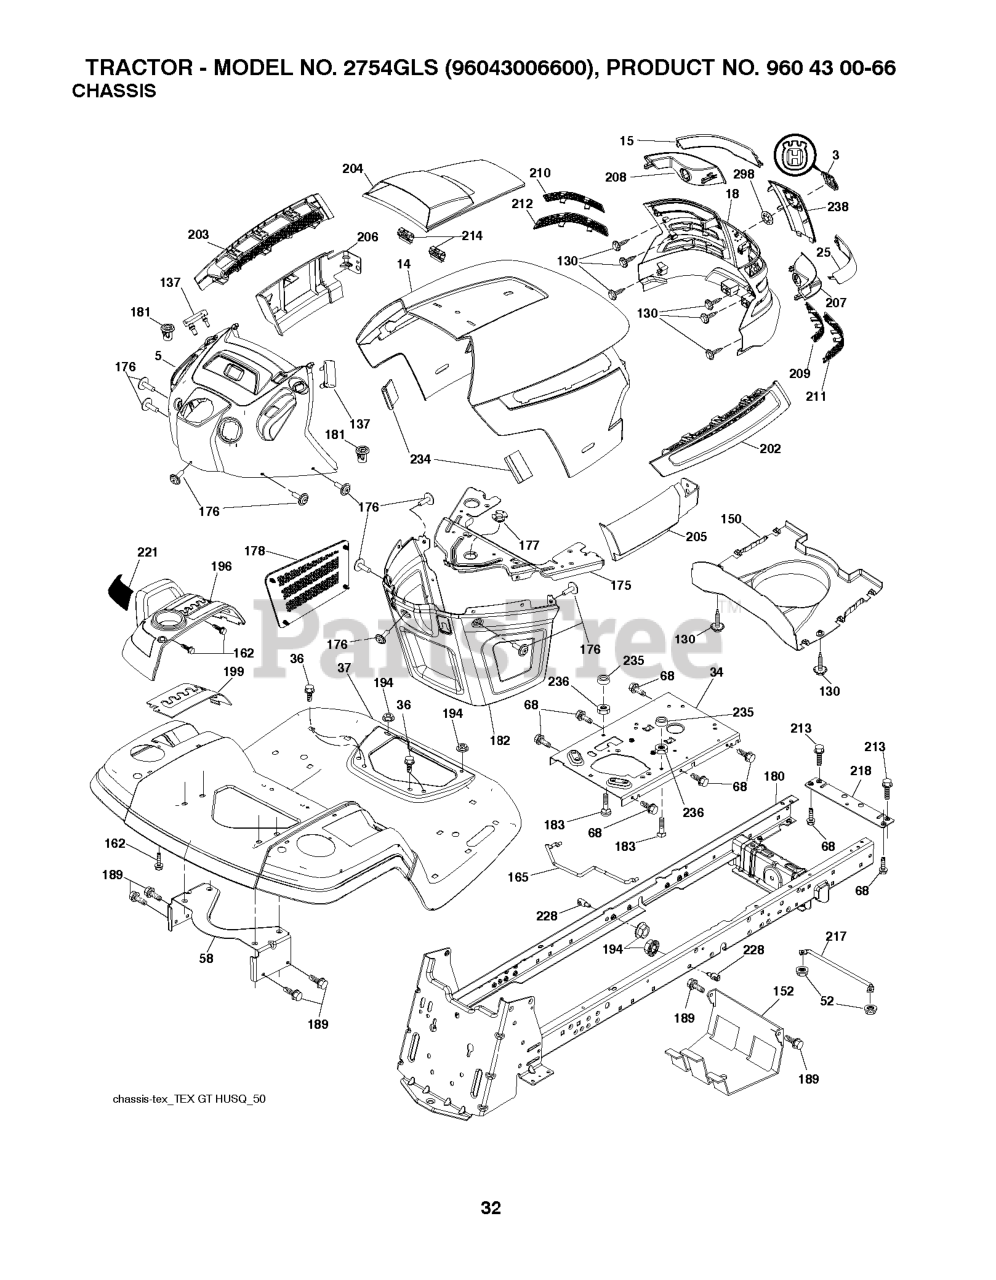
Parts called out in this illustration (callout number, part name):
3	RP LOGO
5	DASH.ASM.GTHUSQTX.RGS.ELECT.CK
14	HOOD
15	LENS.LH.TEX.GT.HUSQ.CL
18	GRILL.ASM.HUSQ.TG/CRD.W/TRIM
25	LENS.RH.TEX.GT.HUSQ.CL
34	PLATE.ENGINE.WELDED.CHASSIS
36	SCREW 5/16"
37	FENDER.PNT.TX.GT.CH/FW.ORANGE
52	LOCKNUT
58	BRKT.SUPPORT.FNDR/TANK
68	Screw 5/16-18 x 1/2 Hex, Self Tapping 5/16-18 x 1/2
130	SCREW.#10 X 0.750.BOS
137	BUMPER DASH
150	AIR.DUCT.HOOD.TEX.GT.HUSQ
152	SHIELD.BROWNING.W/TEX
161	CONSOLE.FUEL.WINDOW.HU
162	SCREW.HI-LO.CONSOLE
165	SUPPORT.TANK.REAR.W/TEX
175	PLATE.CROSSMEMBER.HUSQ
176	SCREW.#10-24X5/8.RN.QU
177	BUSHING, STEERING
178	CARGO.ASM.NET.TXGT.W/C
180	CHASSIS.GT.SLOPED.DRAWBAR.
181	BUSHING.MNT.FEND.CRGO.
182	DASH.LOWER.COMMON.12V.ADAPTOR
183	BOLT.5/16-18X1-1/4 FULL.THREAD
189	SCREW
194	NUT LOCK HEX FLANGE 5/16-18
196	CONSOLE.ASM.DCKLFT.W/RF.HQ.DLR
199	PLATE.DECK.LIFT.HUSQVARNA.GT
202	VENT.SIDE.HOOD.HUSQ.RH.GREY
203	VENT.SIDE.HOOD.HUSQ.LH.GRAY
204	HOOD VENT
205	SKIRT.HOOD.SIDE.HUSQ.RH.GREY
206	SKIRT.HOOD.SIDE.HUSQ.LH.GREY
207	BEZEL.RH.TEX.GT.HUSQ
208	BEZEL.LH.TEX.GT.HUSQ
209	INSERT.HEX.GRILL.HUSQ.GREY
210	INSERT.HEX.GRILL.HUSQ.
211	INSERT.HEX.GRILL.HUSQ.
212	INSERT.HEX.GRILL.HUSQ.
213	BOLT
214	CLIP.RETAINER.TINNER.
217	ROD.PIVOT.HOOD
218	X-PIECE.HOOD.STOP.NON/
221	REFLECTOR.LH.TEX GT HU
228	STUD.FASTNER.W/ANTI-ROTATE
234	BUMPER.HOOD.TEX.HUSQVARNA
235	SPACER FENDER
236	NUT.CENTERLOCK.5/16-
238	TRIM.HUSQ.TG/CRD.SERVICE
298	NUT PUSH M
